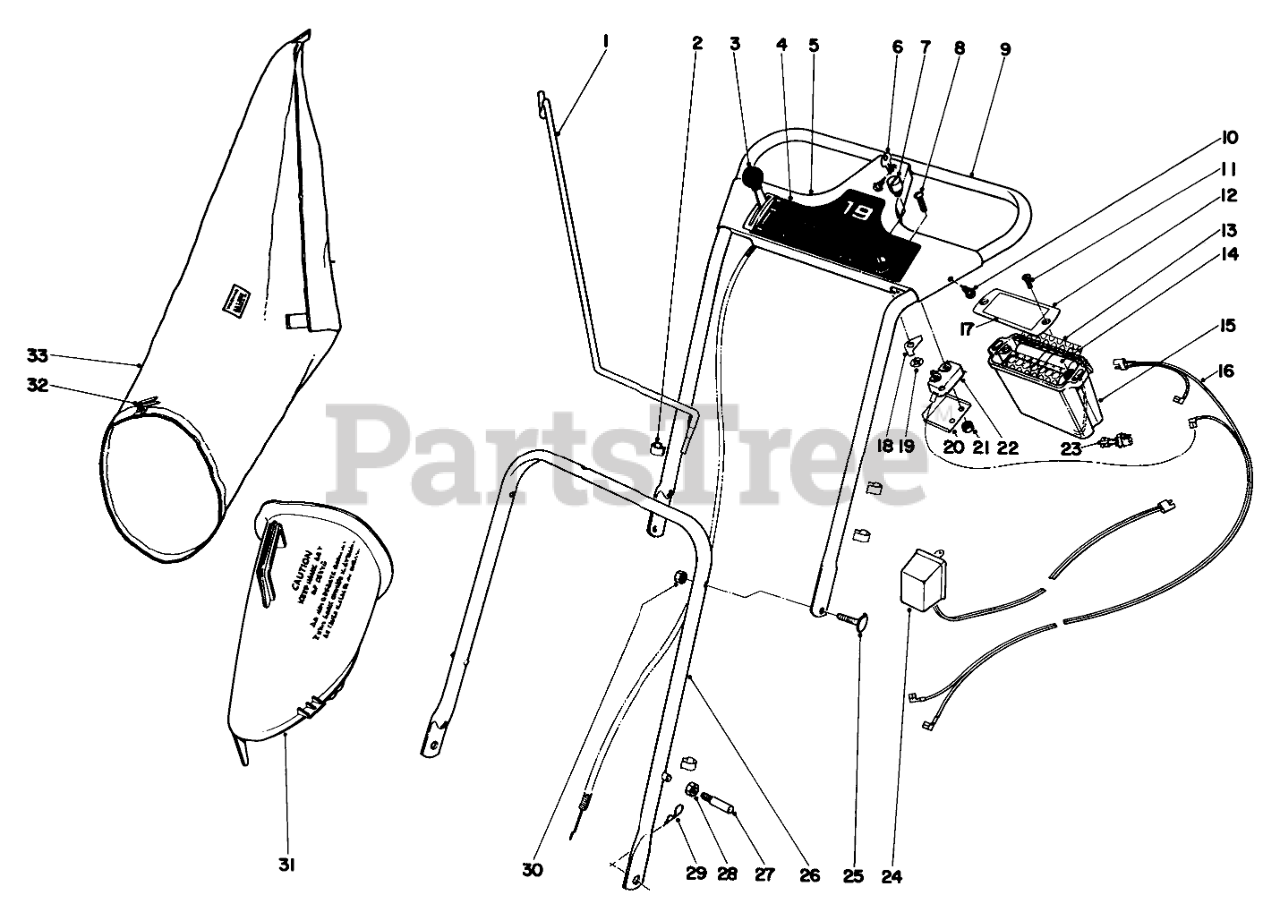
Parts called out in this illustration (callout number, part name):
1	BAG HANGER ROD
2	CONTROL WIRE CLIP
3	Throttle Control
4	Decal
5	Escutcheon Plate
7	Key Hsg.
9	Upper Handle
10	SCREW-HWHTF
12	Cover
13	Spacer
14	Battery Pack
15	Container Pack
16	Wire Harness
17	Decal
20	Cover Switch
21	NUT-KEPS
22	Switch
23	Plug & Wire
24	Charger
25	1-1/4 LG HANDLE SCREW
26	Lower Handle
27	Handle Pin
28	Nut
29	PIN-COTTER, HAIR
30	Nut
31	BAG ATTACHMENT
32	BAG CORD FASTENER
33	Grass Bag Replacement (Incl. Ref. No. 32)
